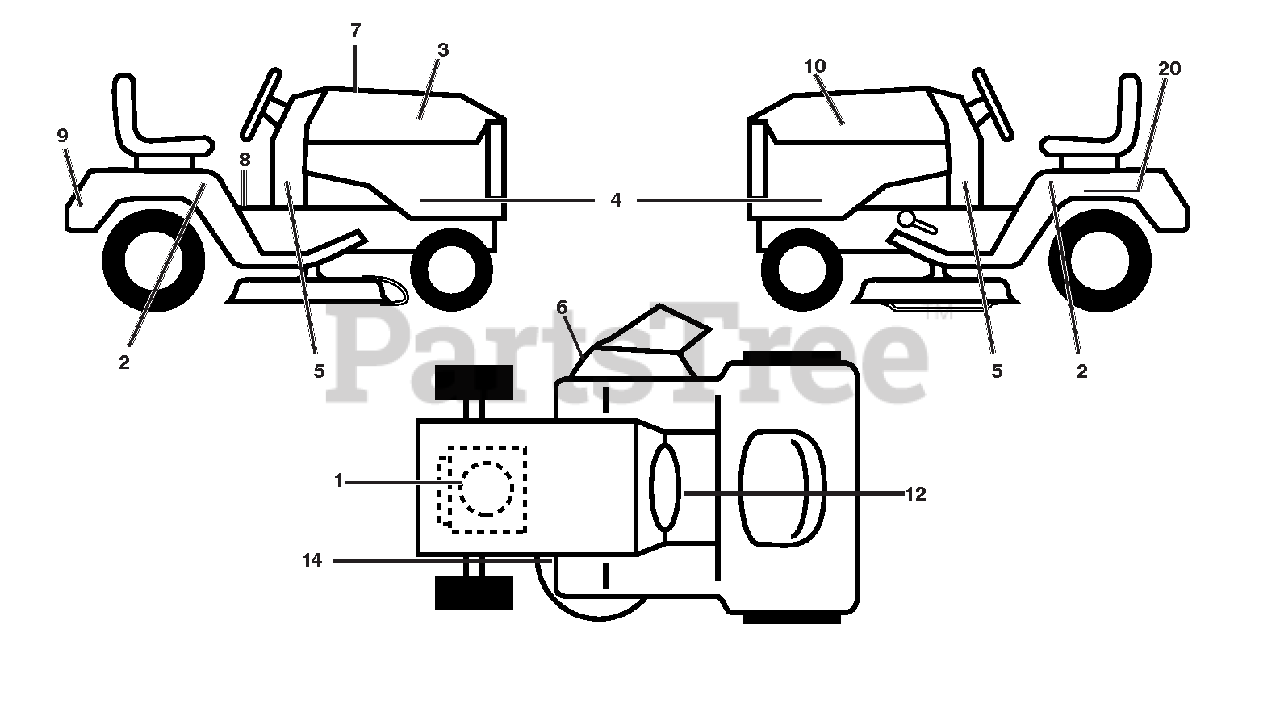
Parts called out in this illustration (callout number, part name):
1	DECAL.ENGINE
2	DECAL.FENDER.SD.GEAR.DR
3	DECAL.HOOD.RH
4	DECAL.SDPNL.PWRDBY B&S.ARIENS
5	DECAL.LOWER.DASH
6	DECAL.WARNING.KEEP.HAND.AWAY
7	DECAL.REPLACEMENT.PARTS
8	DECAL.WARNING.START
9	DECAL.FENDER.REAR.ARIENS
10	DECAL.HOOD.LH
12	DECAL.FENDER
14	DECAL.V-BELT.SCHEMATIC
20	DECAL.BAT.DAN/POI P/L SYM.WPN
